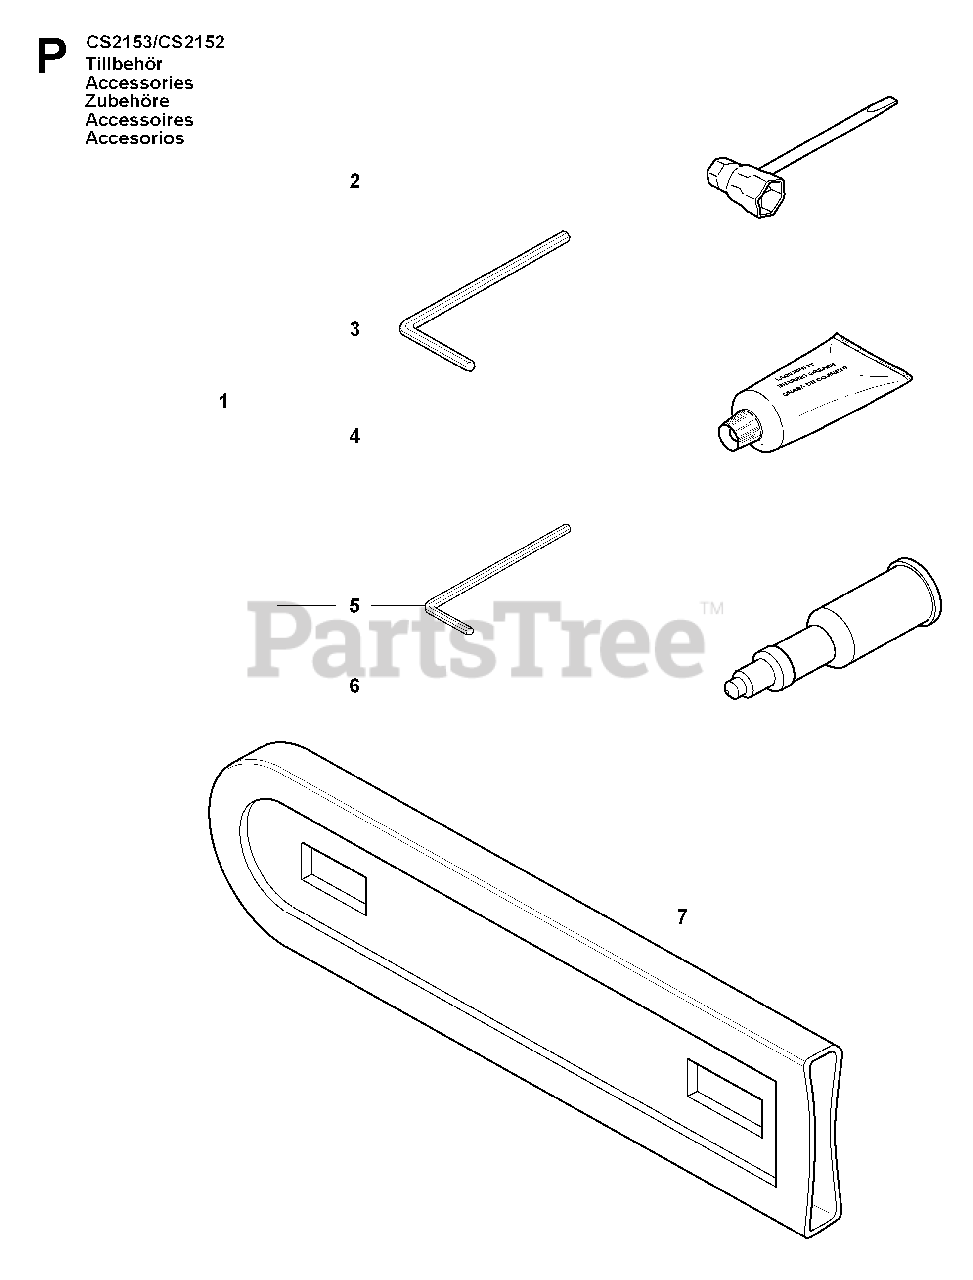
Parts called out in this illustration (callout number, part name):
1	TOOL KIT
2	COMBI TOOL
3	L-SPANNER
5	L-SPANNER
6	GREASE GUN
7	BAR COVER
